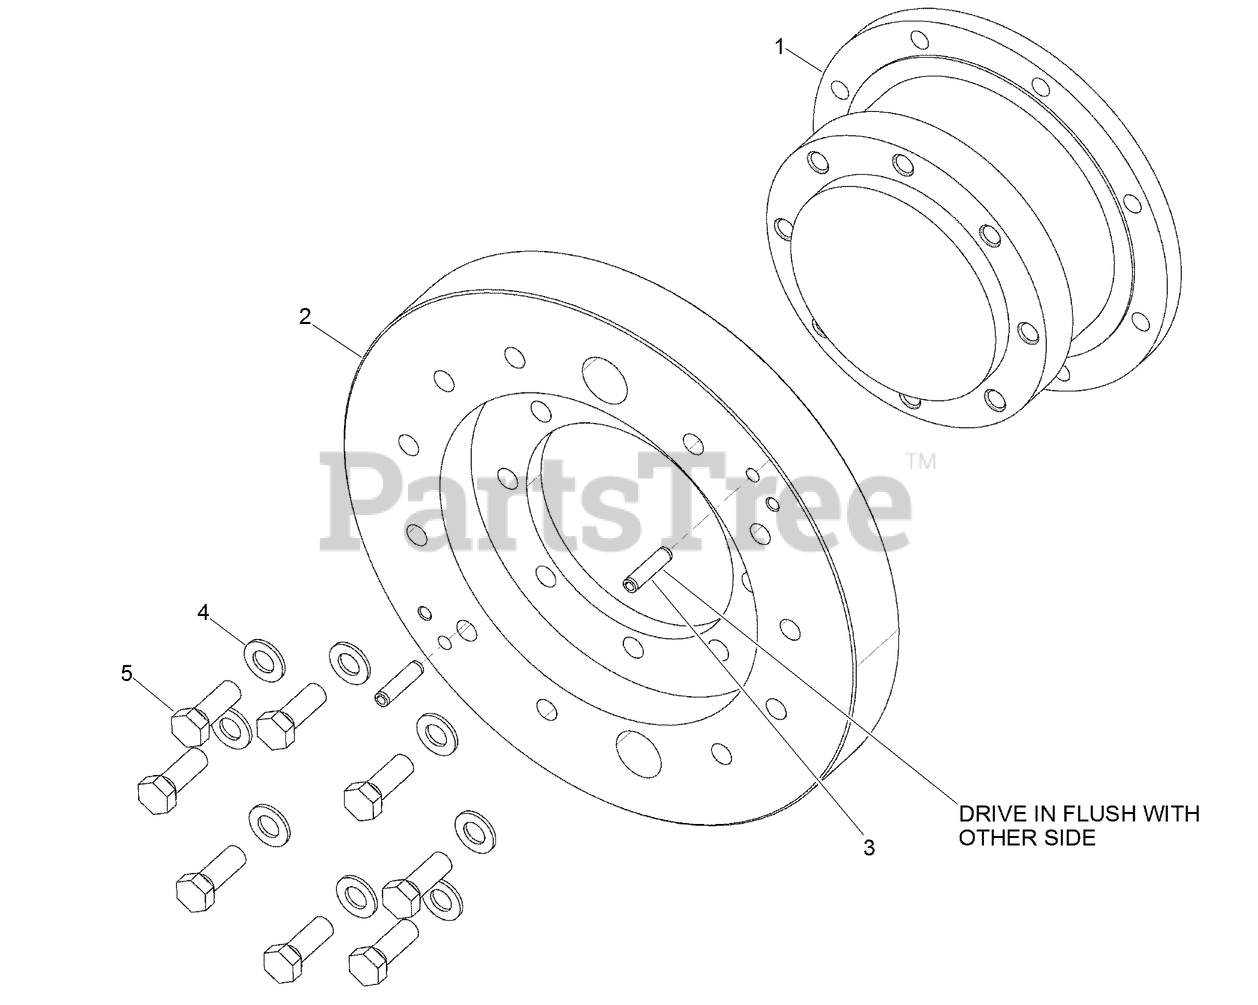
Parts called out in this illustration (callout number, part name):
1	HUB - Model 82N Non-Powered
2	PLATE - Hub Mount
3	PIN - Sltd Spring 0.50 x 2.00 in C-Z
